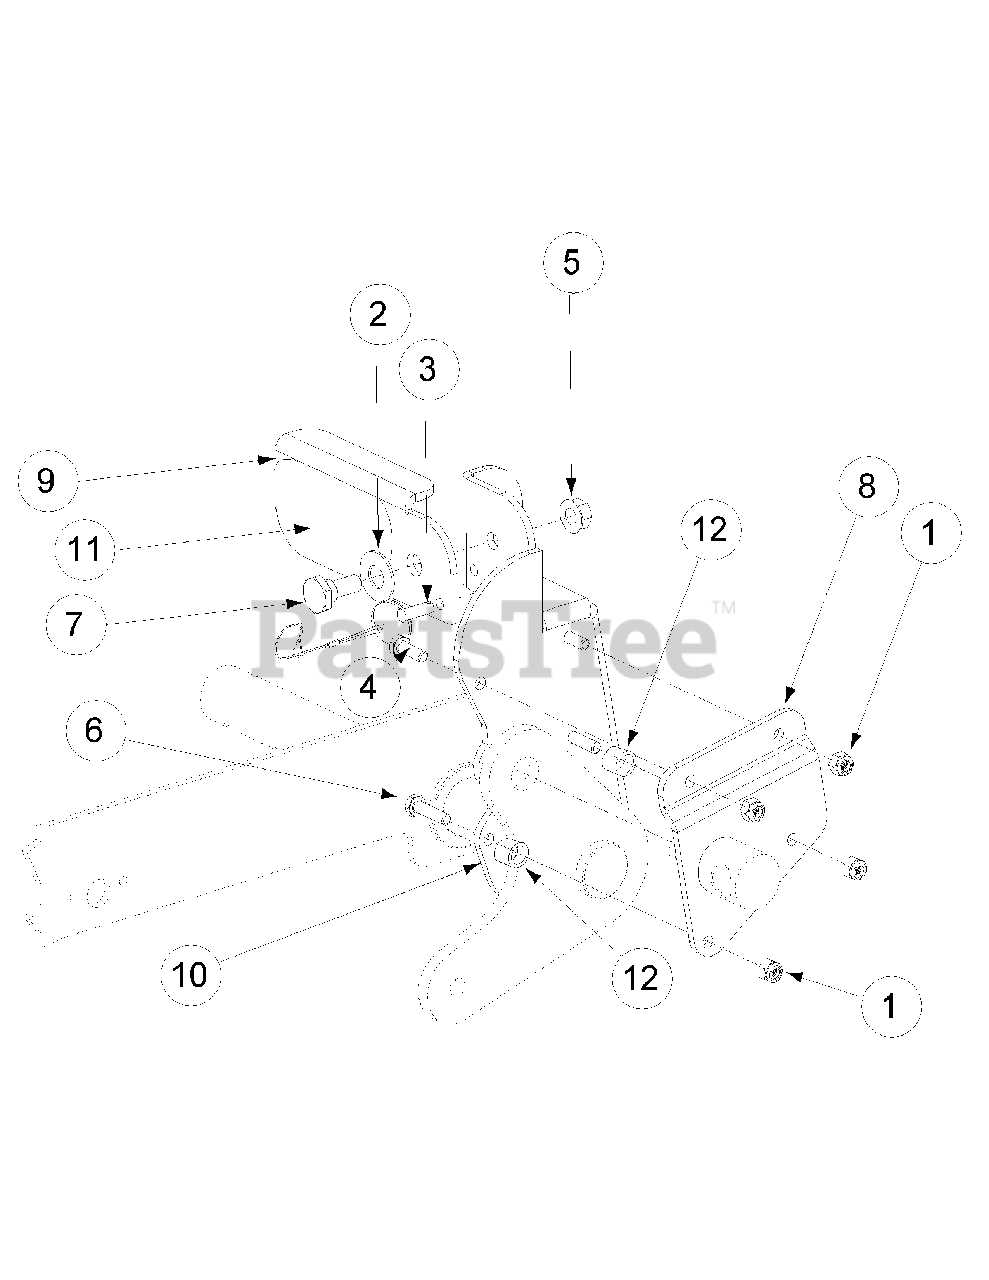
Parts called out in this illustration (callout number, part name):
1	Lock Nut, Nylon Insert, 1/4-20
2	Washer, 1/2 x 1 Shim
3	Detent Pin w/12" Lanyard
4	Hex Cap Screw, 1/4-20, .75
5	Hex Nut, Flange Lock 3/8-16
6	Hex Cap Screw, 1/4-20, 1.00
7	Shoulder Screw, .50 x .27 Lg., 3/8-16
8	Foot Lift Backup Pedal
9	Deck Foot Pedal Lift
10	Deck Foot Pedal Lift
11	Deck Foot Lift Pad
12	Turnbuckle Sleeve
